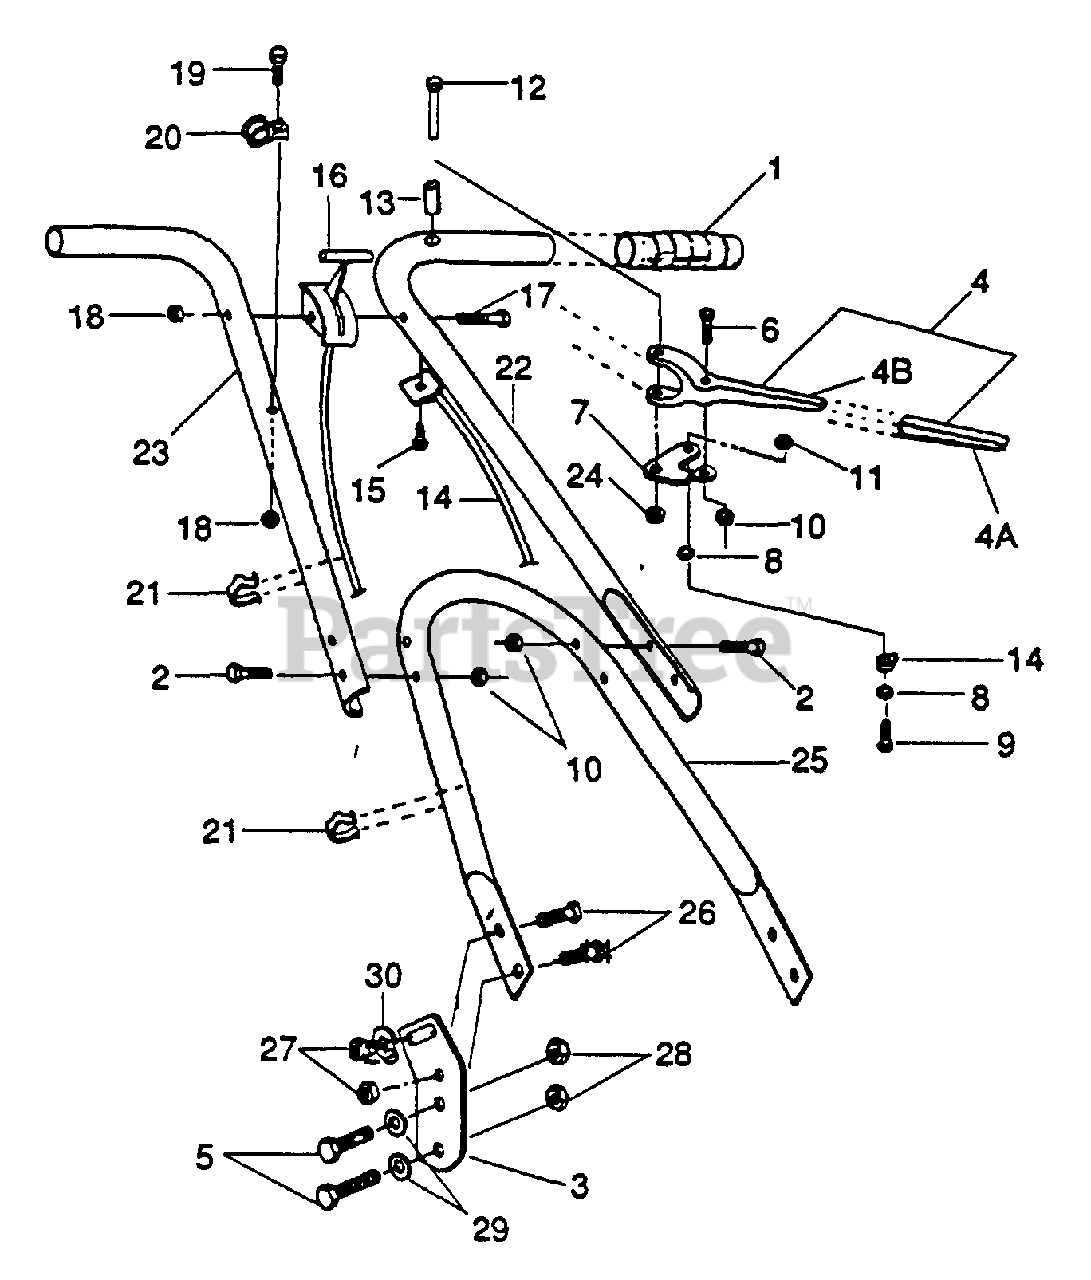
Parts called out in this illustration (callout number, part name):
1	GRIP, HANDLE
2	SCREW - 5/16 X 1-1/2"
3	BRACKET, HANDLE
4	DRIVE LEVER
4A	GRIP
4B	DRIVE LEVER
5	SCREW - 5/16 X 1-1/4"
6	SCREW - 5/16 X 1"
7	CONTROL LEVER PLATE
8	SPACER
9	BOLT - 5/16 X 1/2"
10	LOCKNUT - 5/16"
11	NUT - 1/4"
12	3/16 X 1-7/8" CLEVIS PIN
13	5/16 X 1" ROLL PIN
14	CABLE, CONTROL
15	SCREW, CUTTING - 12
16	THROTTLE CONTROL
17	SCREW - 1/4 X 2-3/4"
18	LOCKNUT - 1/4"
19	SCREW - 1/4 X 2-1/4"
20	GUIDE, ROPE
21	CLIP
22	HANDLE - LEFT
23	HANDLE - RIGHT
24	3/16" PUSH NUT
25	HANDLE - LOWER
26	SCREW - 3/8 X 1"
27	LOCKNUT - 3/8"
28	LOCKNUT - 5/16"
29	BRAKE ADJ. WASHER
30	WASHER - 3/8"
